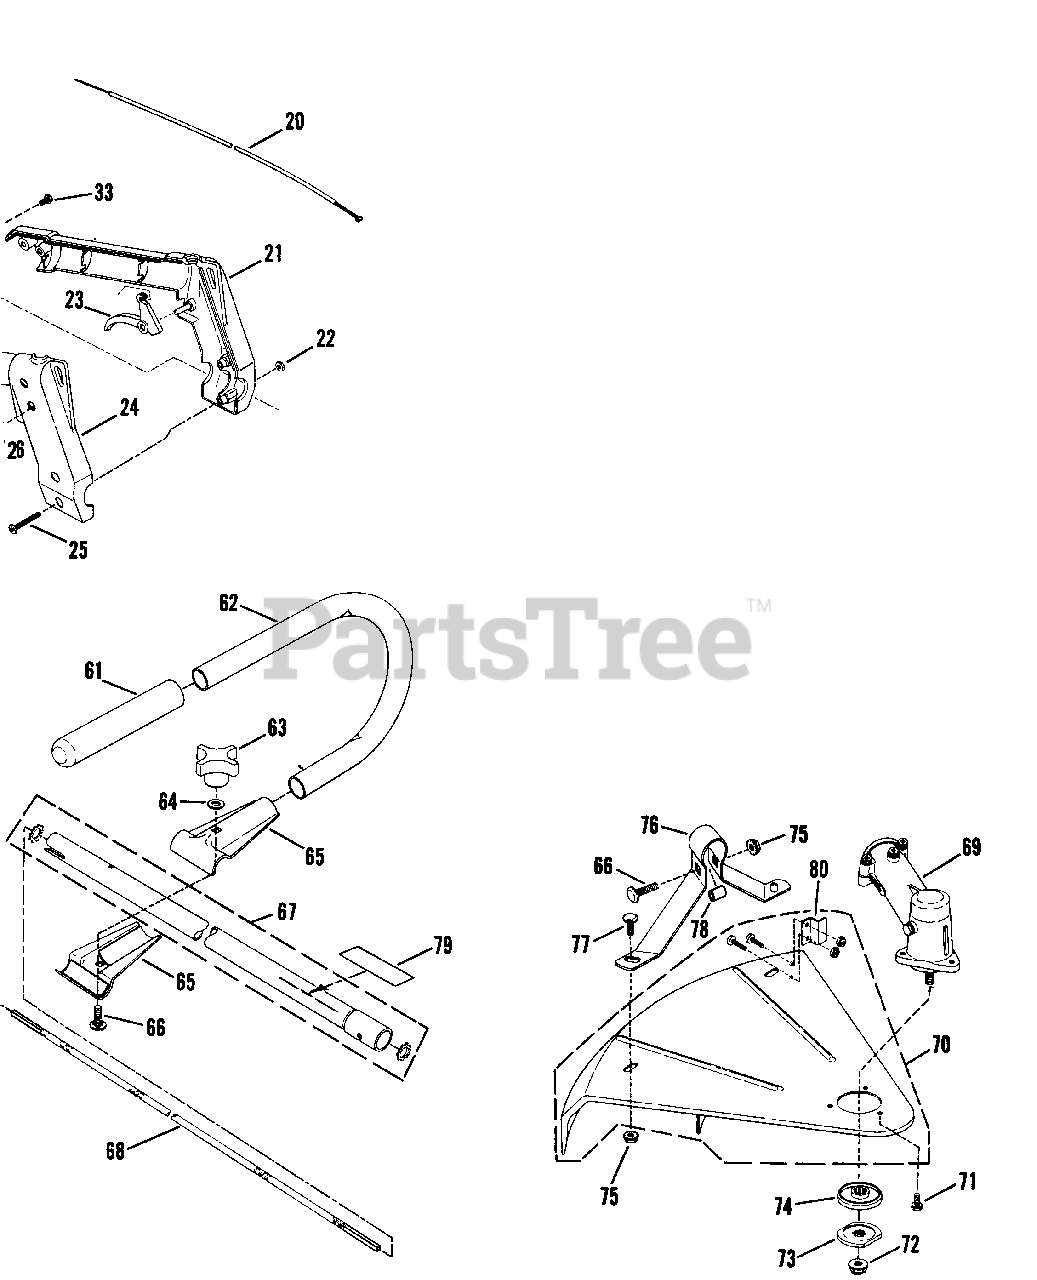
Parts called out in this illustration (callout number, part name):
20	CABLE, Throttle
21	HANDLE, Left Half
22	LOCKNUT, #10-32
23	TRIGGER
24	HANDLE, Right Half
25	SCREW, #10-32x7/8"
26	SCREW, #10-16x3/4"
33	SCREW, Pully Retainer
61	GRIP, "J" HANDLE
62	HANDLE, "J"
64	WASHER
65	CLAMP, Half
66	SCREW, 5/16Cx1 1/2"
67	ASSEMBLY, Liner & Tubing
68	SHAFT, Flex (54.375" x .245", .268" Square Ends x 1")
69	GEAR HEAD
70	SHIELD ASSEMBLY
71	BOLT, Hex Head
72	LOCKNUT
73	HOLDER (B)
74	HOLDER (A)
75	LOCKNUT, 5/16-18 Hex
76	BRACE, Shield
77	CARRIAGE BOLT, 5/16Cx1/2"
79	DECAL-WARNING
80	LINE CUTTER KIT
